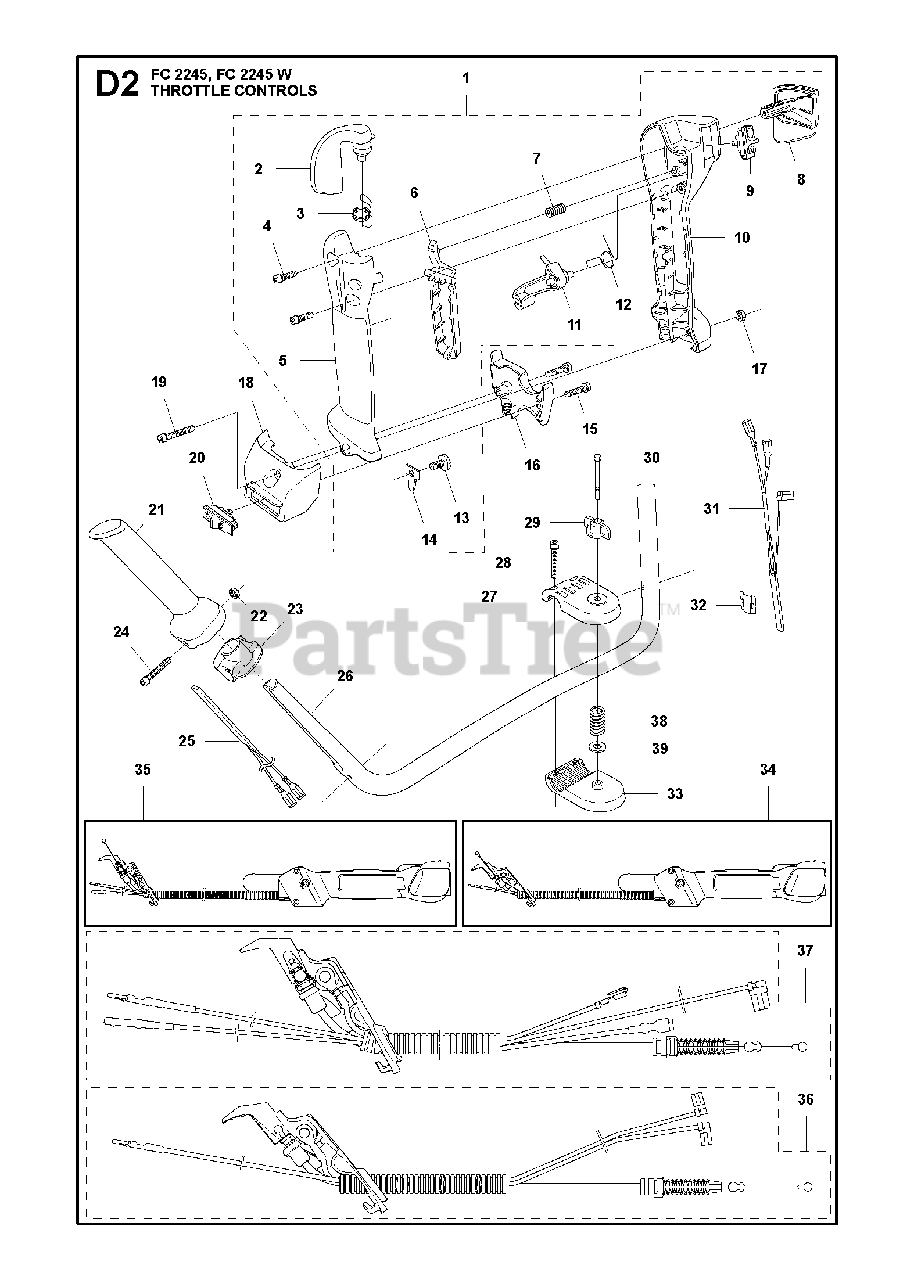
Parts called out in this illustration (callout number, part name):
1	THROTTLE HANDLE
2	THROTTLE TRIGGER
3	RP SPRING
4	SCREW
5	HANDLE
6	THROTTLE LOCK
7	SPRING
8	COVER
9	STOP BUTTON
10	HANDLE
11	LEVER
12	SPRING
13	SCREW
14	HOLDER
15	SCREW
16	HOLDER
17	NUT M6M M5
18	HOLDER
19	SCREW
20	SWITCH (G)
22	NUT M6M M5
25	HEATING ELEMENT
26	RP HANDLE
26	%HANDLE
27	HANDLE BRACKET
30	SCREW 6X70
31	HEATING ELEMENT
32	HOLDER
33	HANDLE BRACKET
